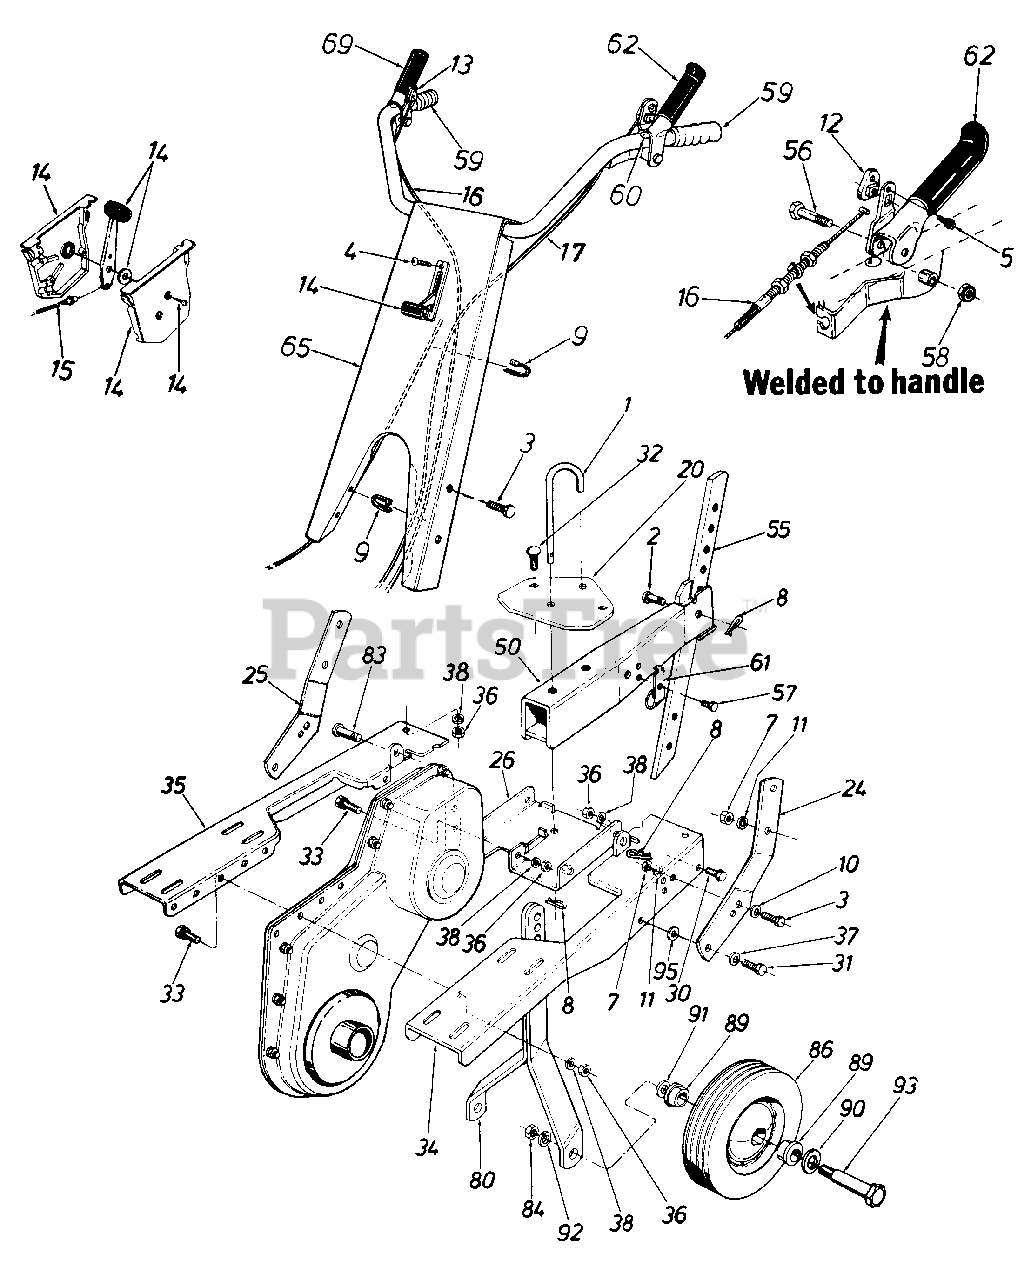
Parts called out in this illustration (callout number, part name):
1	U-Clevis Pin .5" Dia.
2	Clevis Pin 2" Lg.
3	Hex Bolt 3/8-16 x 1.0" Lg.
4	Truss Mach. AB-Tap Scr. #10 x .5" Lg.
5	Hex B-Tap Scr. #10 x .44" Lg.
7	Hex Nut 3/8-16 Thd.
8	Internal Cotter Pin
9	Cable Tie
10	Bell-Wash. 3/8" I.D.
11	L-Wash. 3/8" I.D.
12	Barrel Cable Hold-Down-L.H.
13	Barrel Cable Hold-Down-R.H.
14	Throttle Control Box Ass'y.
15	Throttle Control Wire-35"
16	Clutch Control Cable-
17	Clutch Control Cable-
20	U-Channel Plate
24	Handle Brkt.-L.H.
25	Handle Brkt.-R.H.
26	U-Channel Brkt. Ass'y.
30	Hex Bolt 5/16-18 x .75 Lg.
31	Hex Bolt 3/8-16 x 1.0" Lg.
32	Carr. Bolt 5/16-18 x .75 Lg.
33	Hex Sems Bolt 5/16-18 x 1.0" Lg.
34	Engine U-Channel Ass'y.-L.H.
35	Engine U-Channel Ass'y.-R.H.
36	Hex Nut 5/16-18 Thd.
37	Bell-Wash. 3/8" I.D.
38	L-Wash. 5/16" I.D.
50	Tailpiece Ass'y.
55	Depth Stake
56	Hex Bolt 3/8-24 x 2 0n Lg.
57	Hex TT-Tap Scr. 1/4-20 x 1 /2n Lg
58	Hex Ins. L-Nut 3/8-24 Thd.
59	Grip Handle
60	Push Cap
61	Depth Stake-Spring
62	Clutch Grip Ass'y.-L.H.
65	Handle Ass'y.
69	Clutch Grip Ass'y.-R.H.
80	Wheel Yoke Ass'y.
83	Clevis Pin 2" Lg.
84	Hex Jam Nut 1/2-20 Thd.
86	Wheel Ass'y. 10 x 1.75
89	Flange Brg. .631 I.D.
90	Fl-Wash. .640" x 1.24n x 06n
91	Bell-Wash. 1/2n I.D.
92	L-Wash. 1/2" I.D.
93	Shoulder Bolt .625" Dia. x 2.75"
